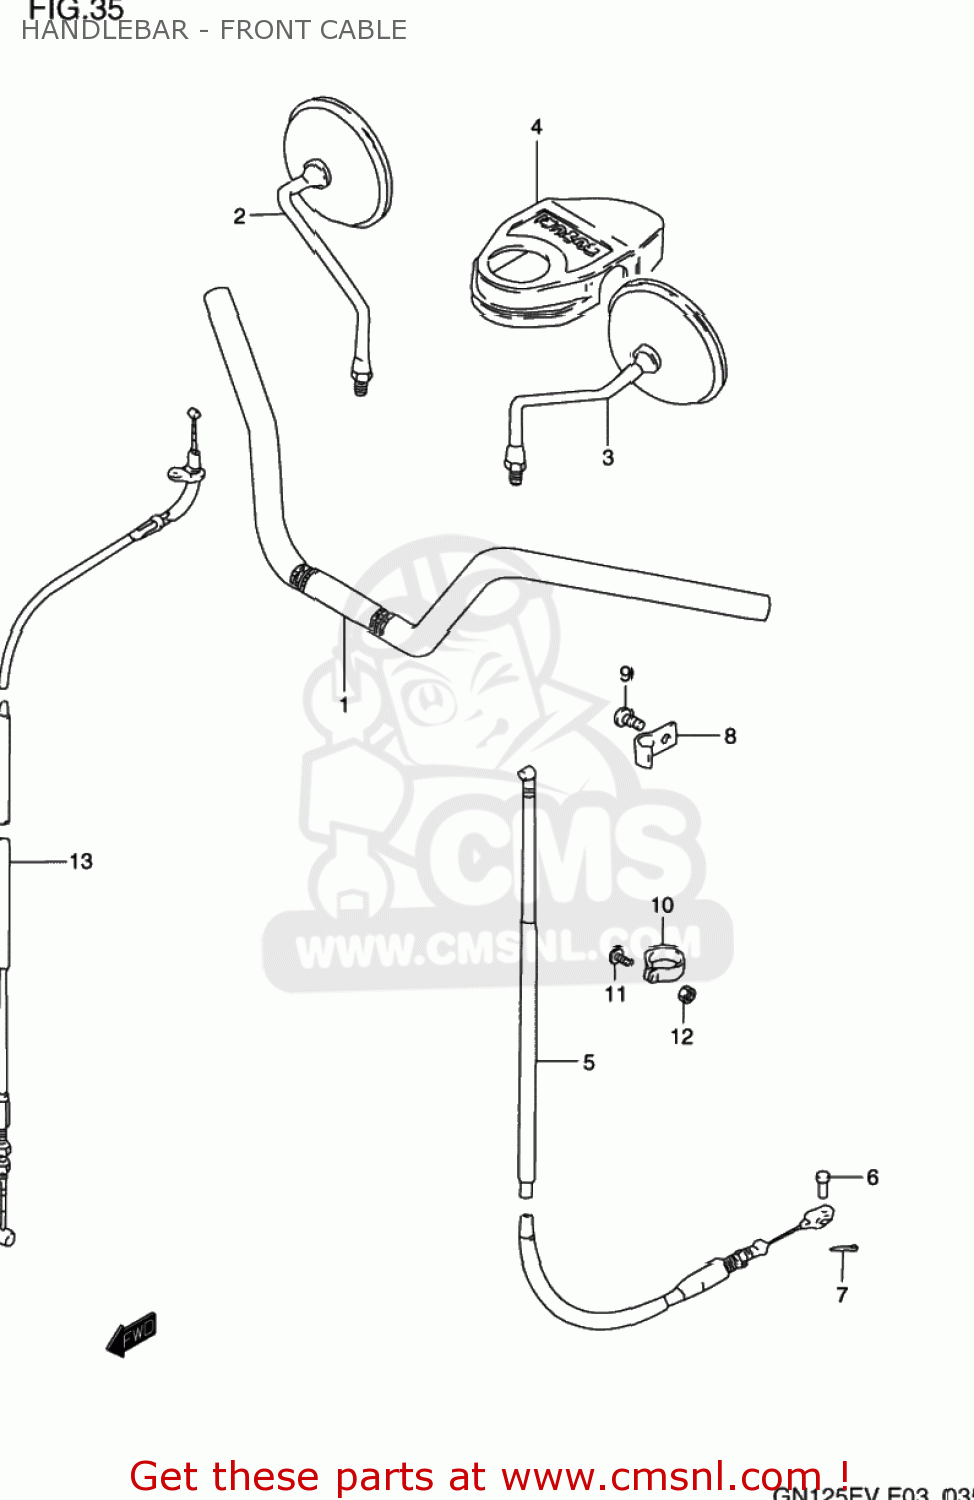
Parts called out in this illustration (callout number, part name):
1	HANDLEBAR
2	MIRROR ASSEMBLY,RIGHT
3	MIRROR ASSEMBLY,LEFT
4	COVER,STEERING HEAD
5	CABLE ASSEMBLY,CLUTCH
6	PIN(L:13)
7	PIN
8	CLAMP,CLUTCH CABLE NO.1
9	SCREW
10	CLAMP,CLUTCH CABLE
11	SCREW
12	NUT
13	CABLE ASSY,THROTTLE
